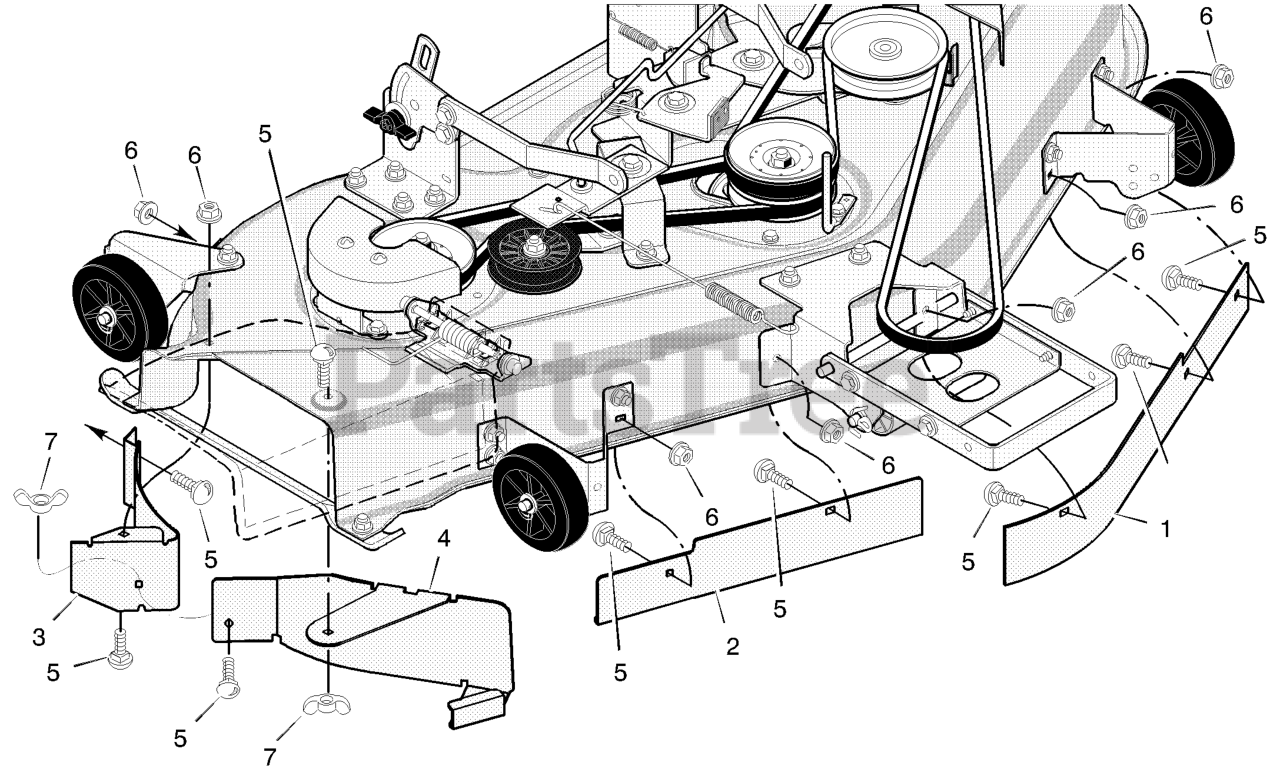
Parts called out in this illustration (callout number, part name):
1	Baffle, Left
2	Baffle, Right
3	Baffle, Inner
4	Plate, Mulcher
5	Bolt, Carriage
6	Nut, Flange
7	Wingnut
